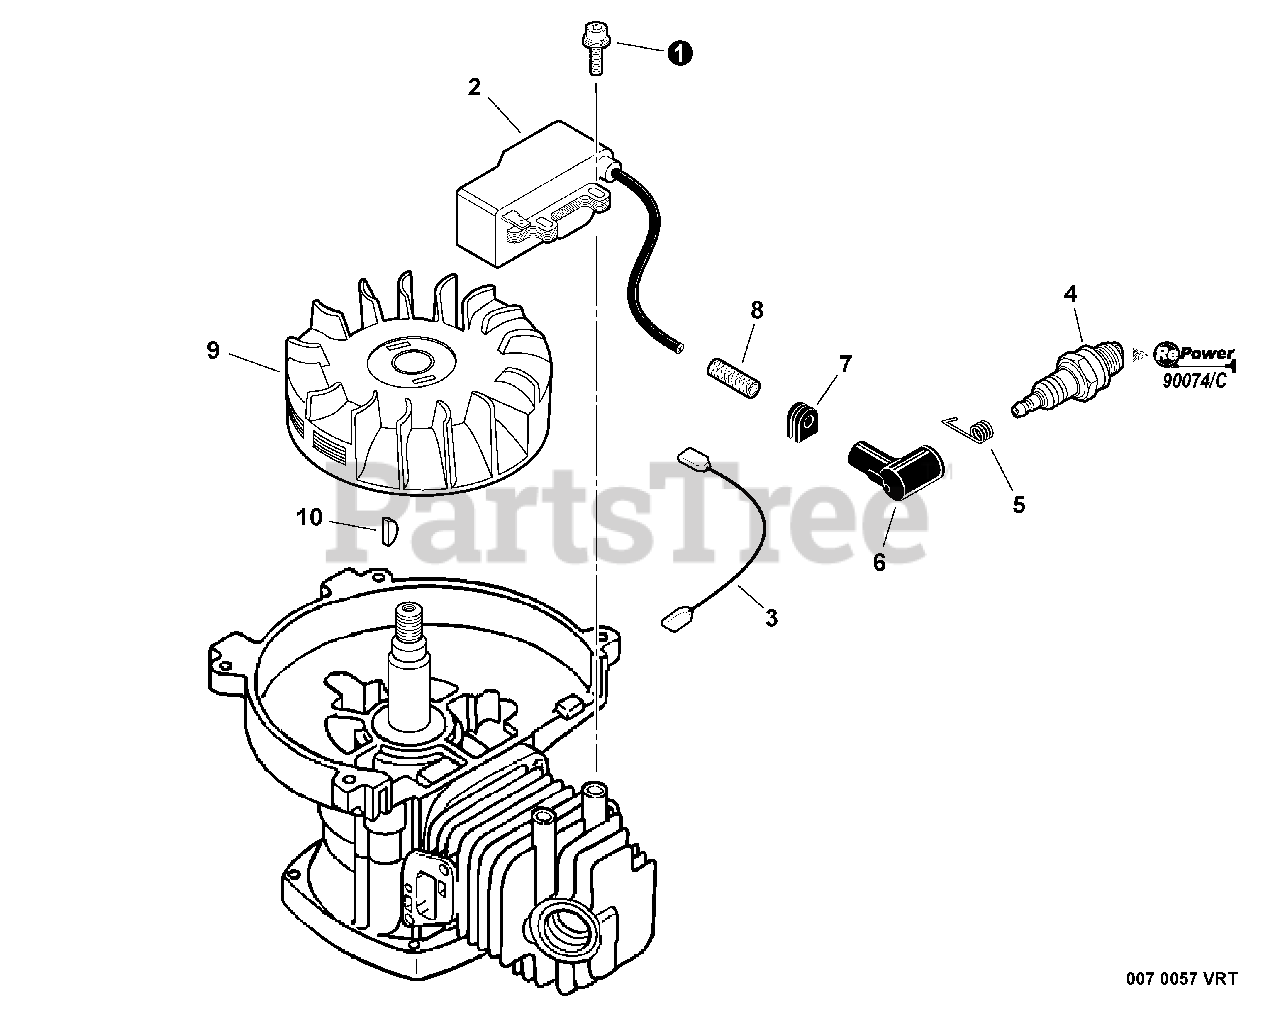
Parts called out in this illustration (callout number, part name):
1	BOLT 4×20
2	COIL, IGNITION
3	LEAD
4	SPARK PLUG - BPM8Y
4	SPARK PLUG - BPMR8Y
5	TERMINAL, SPARK PLUG
6	CAP, SPARK PLUG
8	TUBE, INSULATOR
9	FLYWHEEL
11	TUNE-UP KIT - REPOWER
